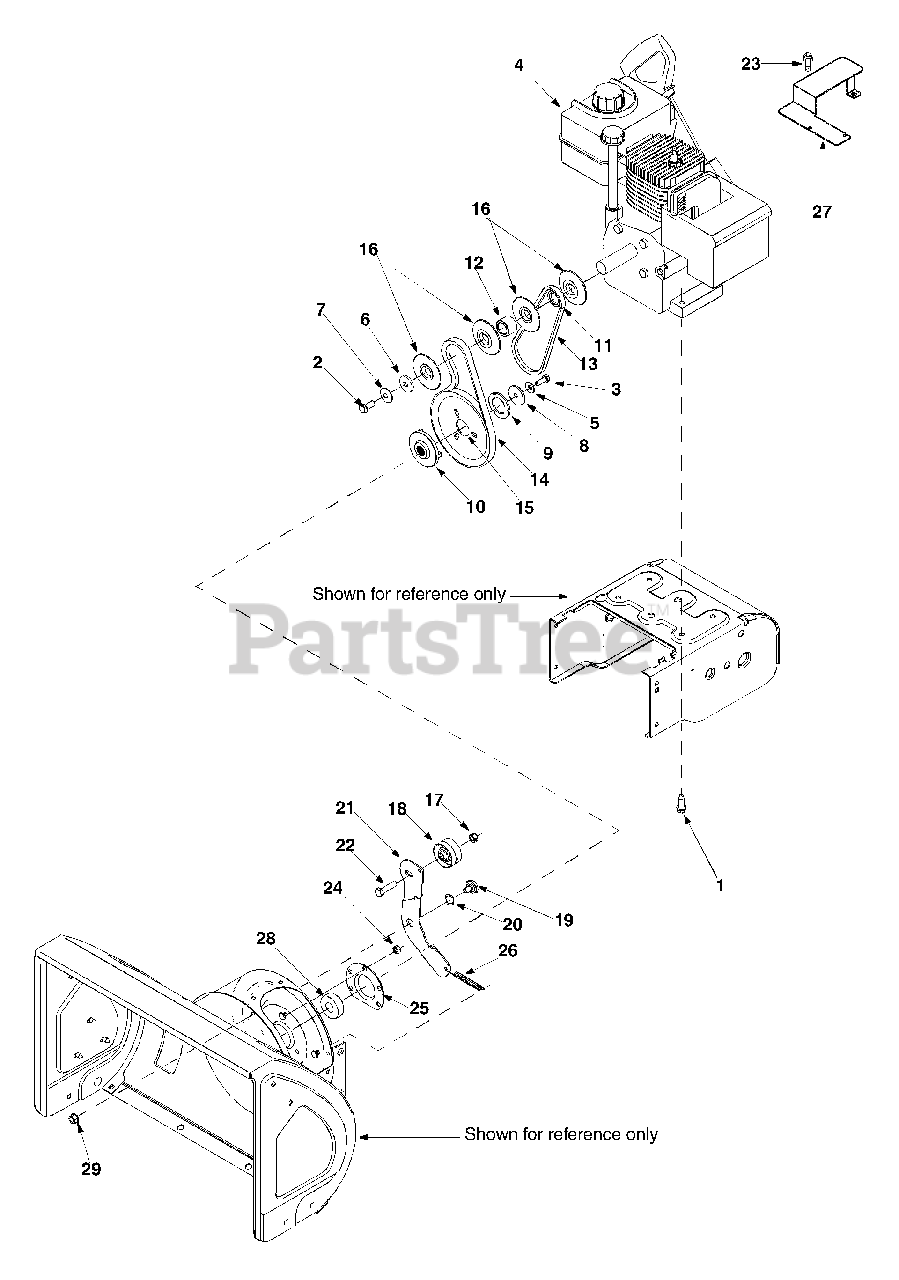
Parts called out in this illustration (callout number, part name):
1	TT Sems Screw 3/8-16 x 1.0"
2	Hex Bolt 3/8-24 x 0.875"
3	Lock Bolt 5/16-24 x 0.875"
4	Engine
5	Bell Washer,.340 x.872 x.060
6	Flat Washer,.406ID x 1.25OD
7	Bell Washer,.390 x 1.13 x.062
8	Flat Washer,.34ID x 1.50OD
9	Special Washer, 1.285 x 2.0 x.119
10	Pulley: Adapter,.75 Dia.
11	Spacer,.8760ID x 1.25OD x.1900
12	Spacer,.8760ID x 1.25OD x.86
13	V-Belt, 3/8 x 21.108 Lg.
14	V-Belt, 3/8 x 26.375 Lg.
15	Auger Pulley
16	Pulley Half
17	Hex Lock Nut 3/8-16
18	Flat Idler
19	Shoulder Screw 3/8-16
20	Wave Washer
21	Auger Idler Bracket
22	Hex Bolt 3/8-16 x 1.50"
23	Screw, #10-16 x.500
24	Flange Lock Nut, 5/16-18
25	Bearing Housing
26	Extension Spring
27	Heat Shield
28	Ball Bearing
29	Flange Lock Nut, 3/8-16
